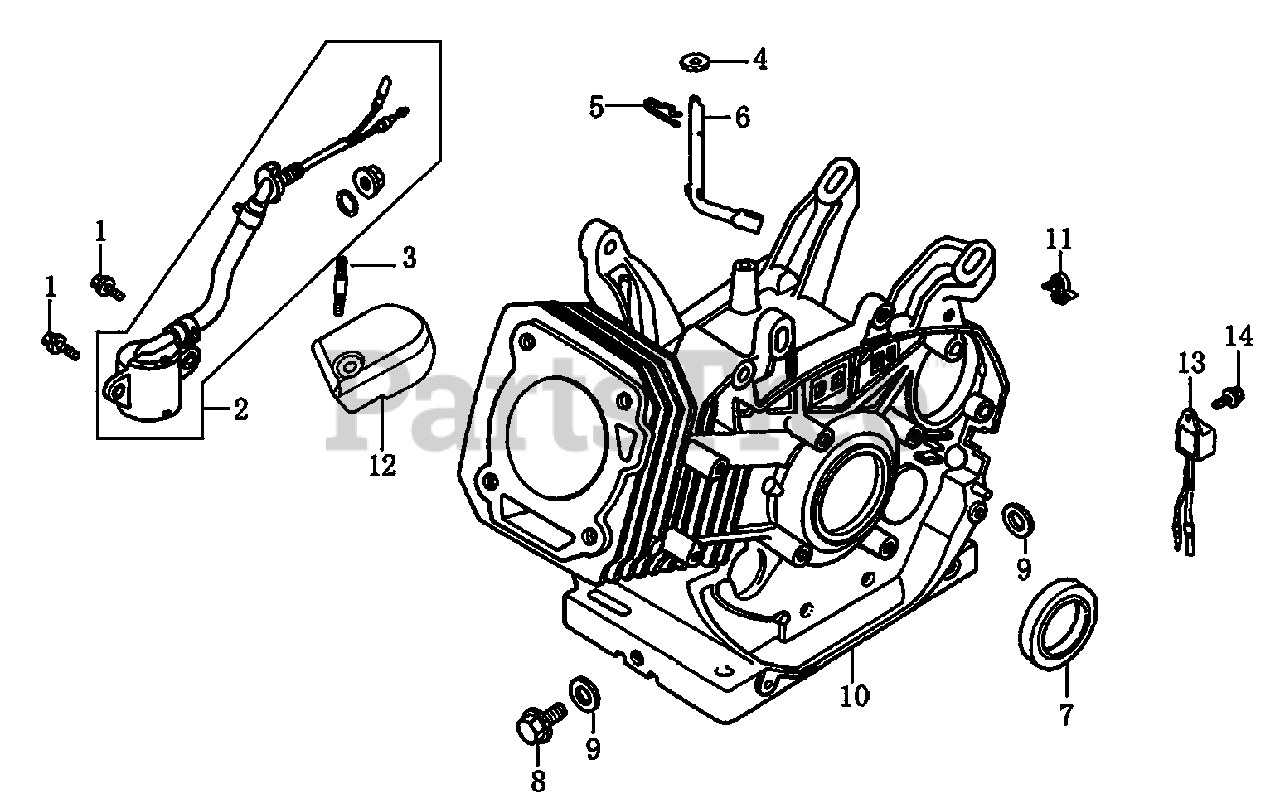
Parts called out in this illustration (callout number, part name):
1	BOLT, FLANGE
2	SWITCH ASSY., OIL LEVEL
3	BOLT, STUD, EXHAUST
4	WASHER,8*16*1.2
5	PIN, LOCK, 10MM
6	SHAFT, GOVERNOR ARM
7	OIL SEAL 30x46x8
8	BOLT, DRAIN PLUG
9	WASHER, DRAIN PLUG, 12MM
10	CRANKCASE
11	HOLDER, STOP SWITCH
12	COVER, WIRE
13	ALERT UNIT,OIL
14	BOLT, FLANGE, 6x12
